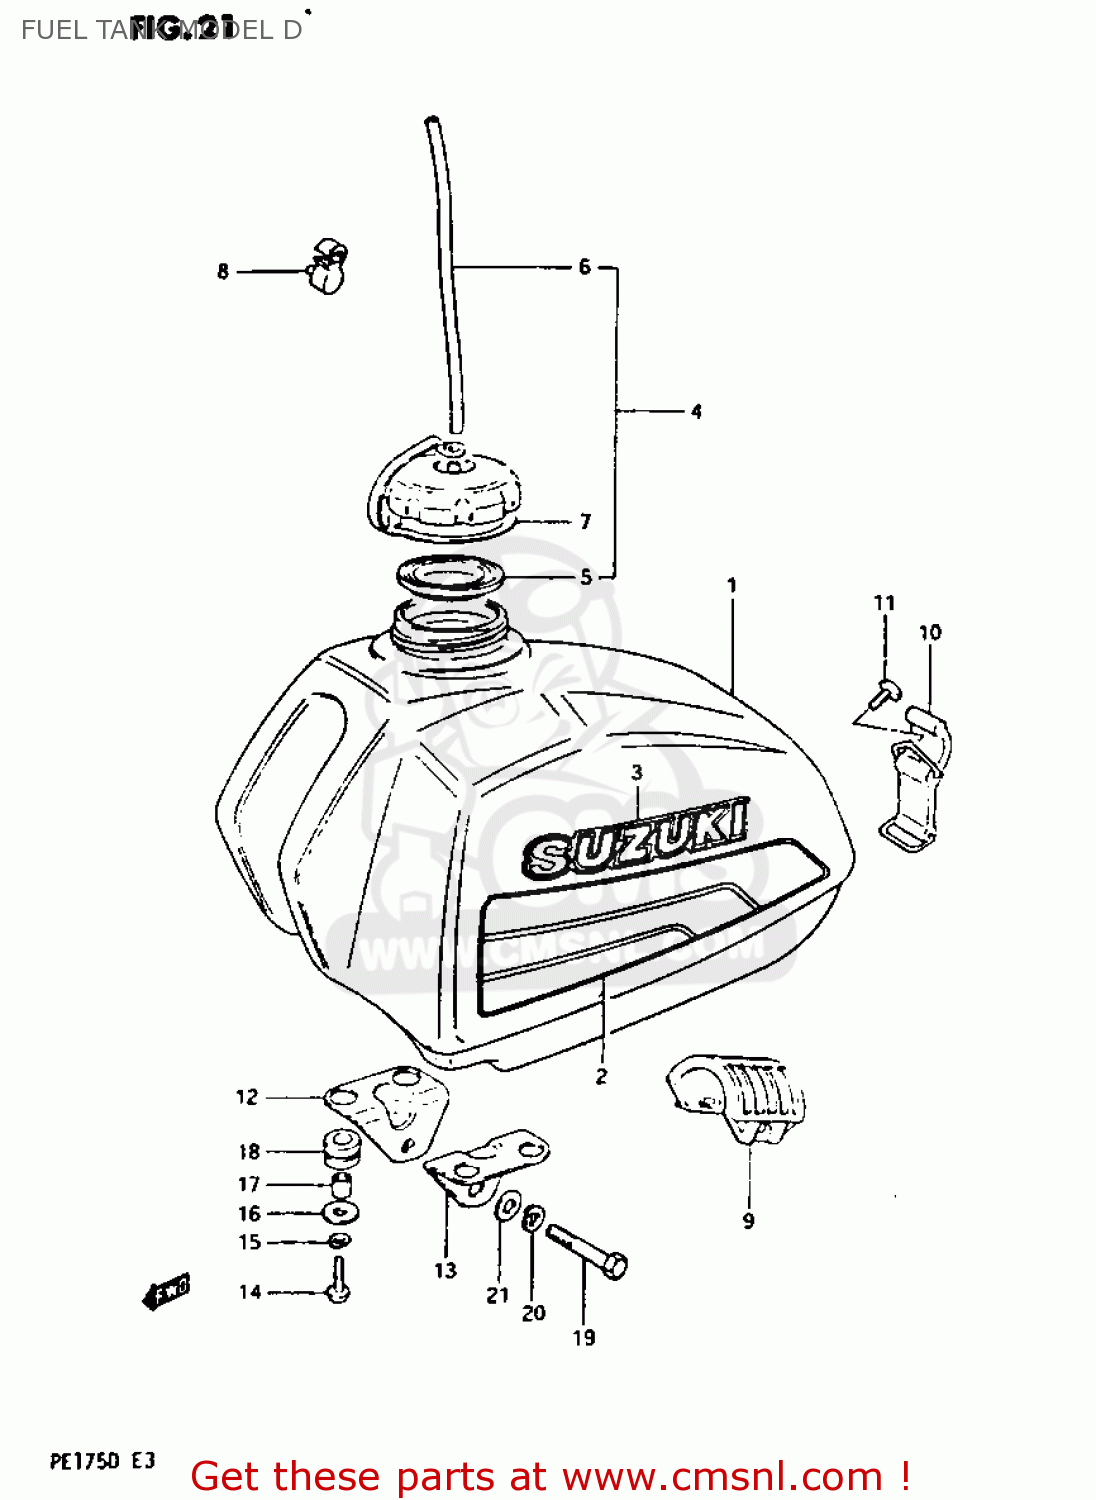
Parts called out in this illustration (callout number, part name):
1	TANK ASSEMBLY,FUEL
2	TAPE SET,FUEL TANK
3	EMBLEM
4	CAP,FUEL TANK
5	GASKET,FUEL TANK CAP (NAS)
6	HOSE
7	BAND,FUEL TANK CAP
8	CLAMP,BREATHER HOSE
9	CUSHION,FUEL TANK
10	BAND,FUEL TANK,REAR
11	SCREW(6X18)
12	BRACKET,FUEL TANK,LOWER
13	BRACKET,FUEL TANK
14	SCREW
15	WASHER,LOCK
16	WASHER (6.5X24X1.6)
17	SPACER(6.8X12X11)
18	CUSHION
19	HEXAGON BOLT 8X80
20	LOCK WASHER
21	WASHER
